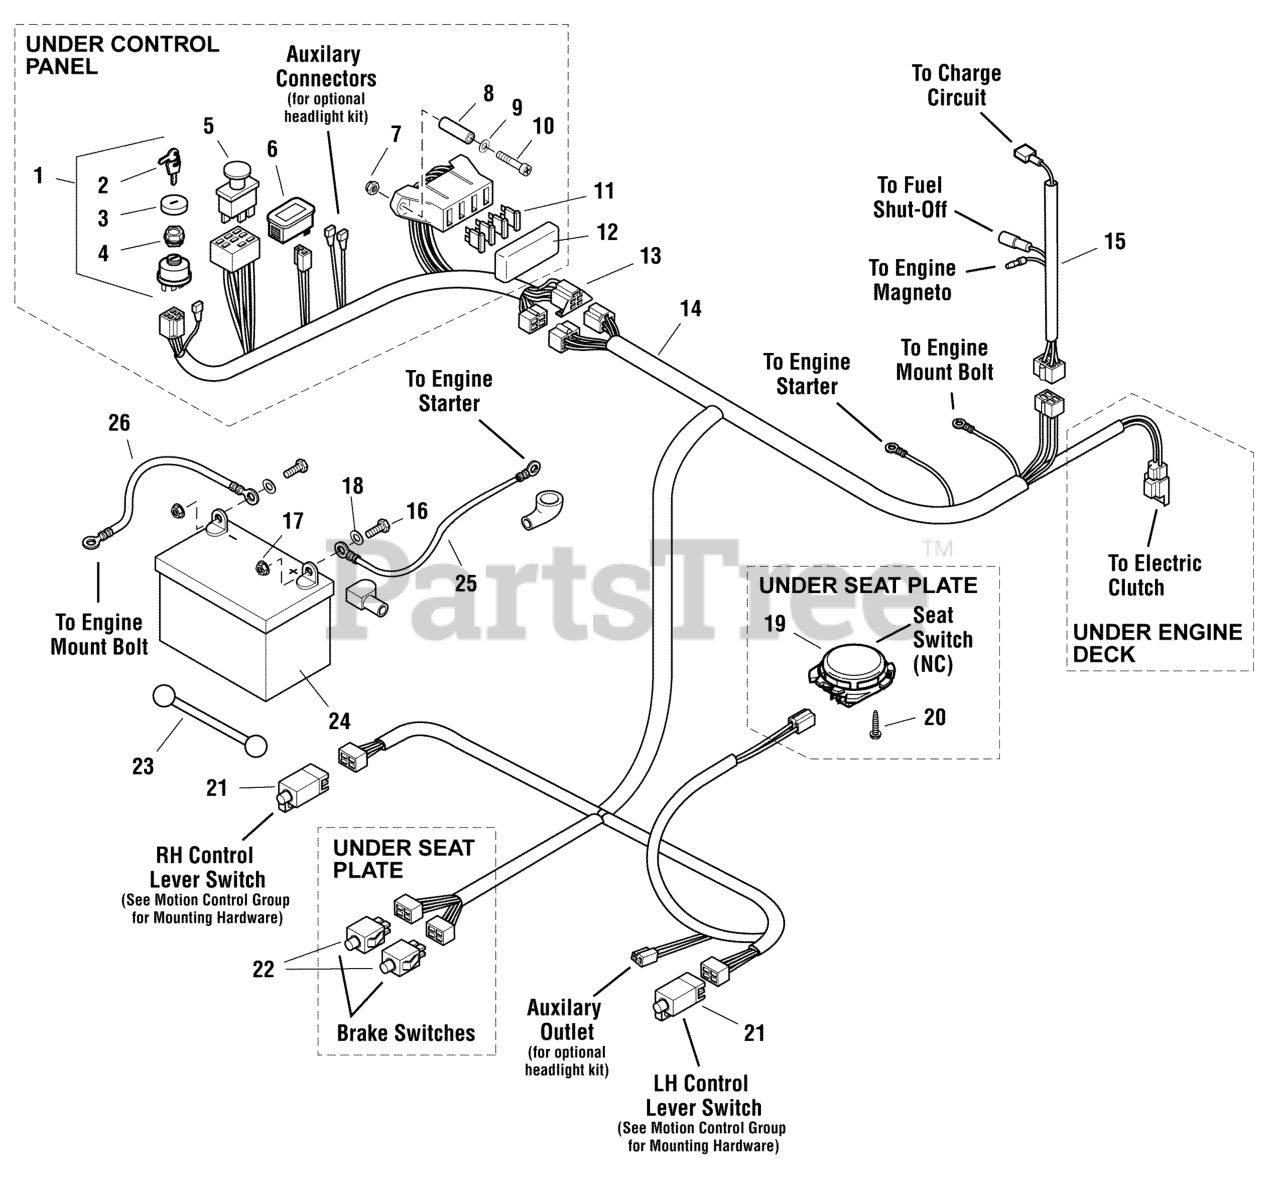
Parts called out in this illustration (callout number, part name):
1	SWITCH, IGNITION, 6 POST
2	KEY, IGNITION MOLDED SET
3	COVER, PLASTIC, SNAP ON
4	PLASTIC NUT
5	SWITCH, BLADE ENGAGEMENT
6	HOURMETER, Digital
7	NUT, #10-24 Hex Nylon Lock
8	SPACER, .20 x .38 x 1.25
9	WASHER, #10 SAE
10	SCREW, #10-24 x 2"
11	FUSE, 20A
12	FUSE BLOCK COVER
13	WIRE HARNESS, FUSE BLOCK - IS2000
14	WIRE HARNESS, MAIN, IS1500ZX
15	WIRE HARNESS, BIG BLOCK KAWI JUMPER
16	BOLT, 1/4-20 x 3/4
17	BOLT, 1/4-20 x 3/4
18	WASHER, 1/4 SAE
19	SWITCH, NC, W/ TWIST-IN BASE
19	SWITCH, NC, W/ BOLT-IN BASE
20	BOLT, Hex Washer Head PLASTITE, 1/4 X 1/2
21	SWITCH, PLUNGER, N.O./N.C.
22	SWITCH, DP NO/NC SNAP-IN
23	STRAP, BATTERY, 14 LONG, Rubber
24	BATTERY, Lawn & Garden, 12V (BCIU1, 340 CCA)
25	POSITIVE (+) BATTERY CABLE, 15"
26	BATTERY CABLE, NEG, 22, 1/4-5/16
